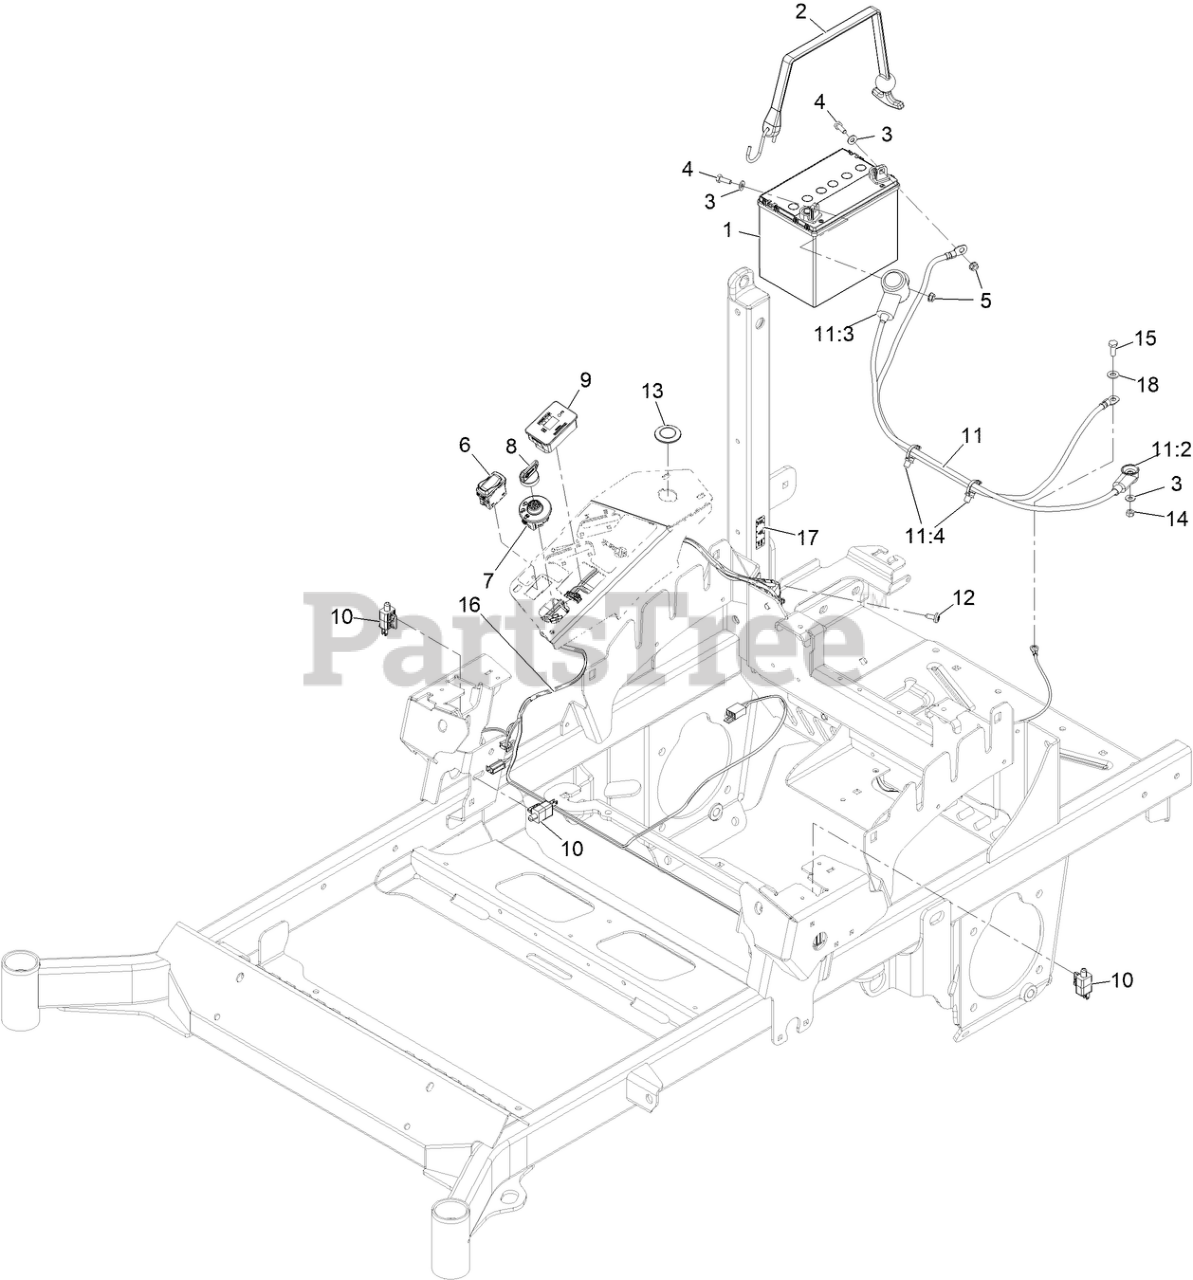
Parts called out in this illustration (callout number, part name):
1	Battery
2	STRAP, BUNGEE
3	WASHER-FLAT
4	SCREW-HH
6	SWITCH-ROCKER, ON-NONE-ON
7	SWITCH-IGNITION
8	KEYS-IGNITION (SPARE PAIR
8	KEY-IGNITION
9	MODULE ASM
11	HARNESS-BATTERY
11:2	Insulator-Terminal, Red
11:3	Insulator-Terminal, Red
11:4	CLIP-TIE
12	SCREW-TORX
14	NUT-HEX
15	SCREW-HH
16	Harness-Main
17	DECAL-FUSE
18	WASHER-PLAIN
